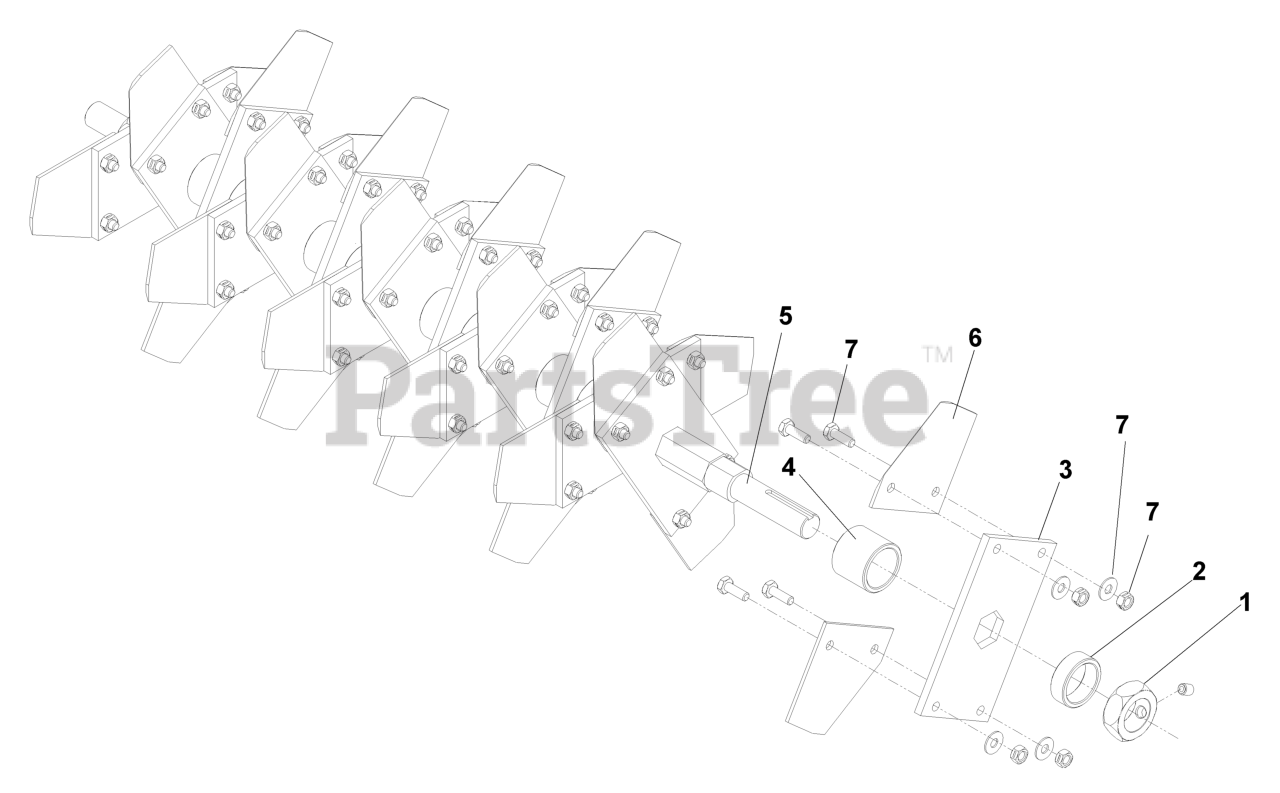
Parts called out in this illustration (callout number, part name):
1	JAM NUT W/SET SCREW
2	END SPACER
3	BLADE MOUNTING PLATE
4	SPACER - LONG
6	30 DELTA SET W/HARDWARE
7	SCREW & NUT (60 EACH)
